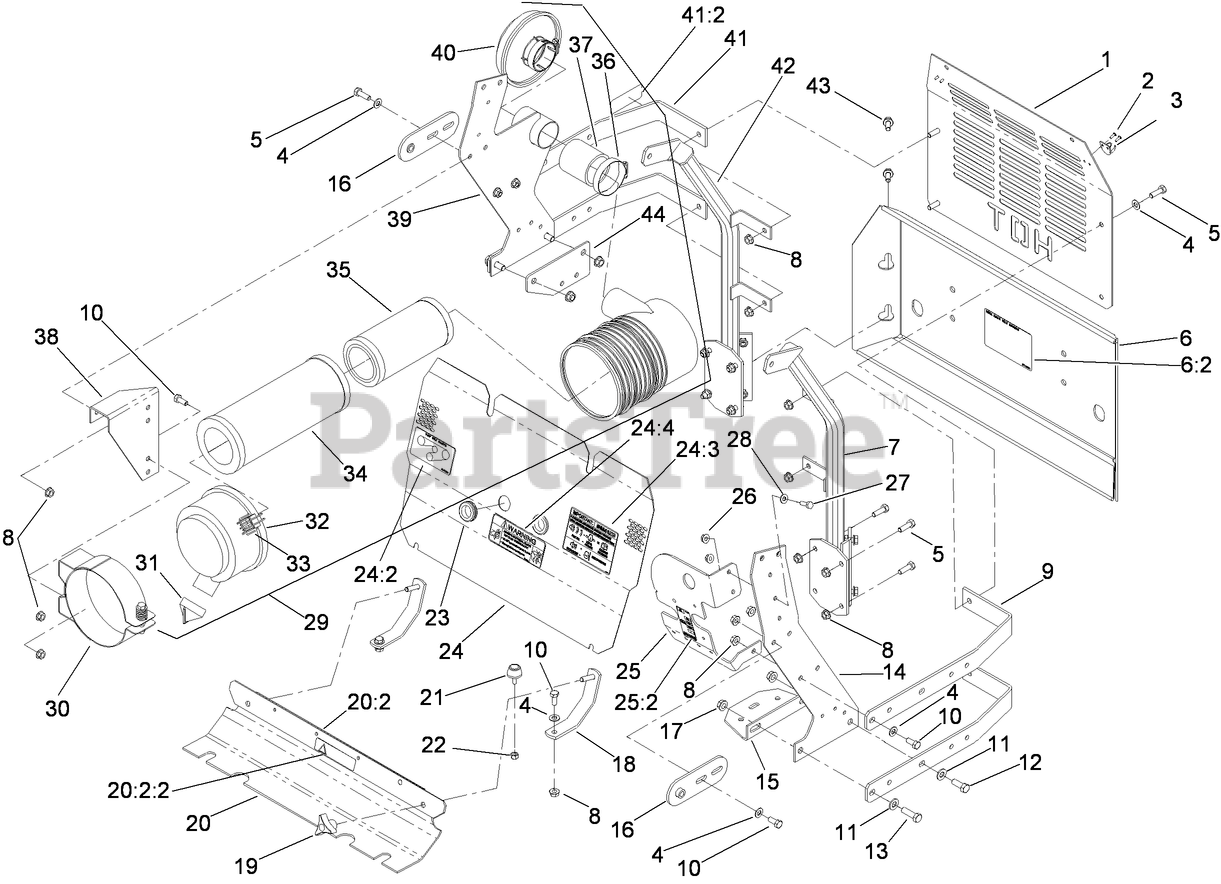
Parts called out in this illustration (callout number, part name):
1	GUARD-MUFFLER
2	RIVET
3	KEEPER-LATCH, RUBBER
4	WASHER-PLAIN
5	SCREW-HH
6	REAR BUMPER ASM
6:2	DECAL-BELT ROUTING, DECK DRIVE
7	FRAME-UPPER, LH REAR
8	NUT-HF
9	BAR-MOUNT FRAME, RADIATOR
10	SCREW-HH
11	WASHER-FLAT
12	SCREW-HH
13	SCREW-HH
14	MOUNT-SIDE, LH
15	BRACKET-BOTTLE
16	SHACKLE-HINGE
17	NUT-HHF, WHIZ
18	MOUNT-BELT SHIELD, ENGINE
19	KNOB-3 PRONG
20	ENGINE BELT SHIELD ASM
20:2	STRIP-SHIELD, BELT
20:2:2	DECAL-COVER, MISSING
21	BUMPER-RUBBER
22	NUT-LOCK, NI
23	GROMMET-RUBBER
24	ENGINE ACCESS PANEL ASM
24:2	DECAL-BELT ROUTING, PUMP
24:3	DECAL-BUZZER, WARNING
24:4	DECAL-DEVICES, ROTATING
25	FUSE/RELAY BRACKET ASM
25:2	DECAL-FUSE
26	NUT-HF
27	SCREW-HH
28	WASHER-FLAT
29	FILTER-AIR
30	BRACKET-FILTER, AIR
31	VALVE-EJECTOR, DUST
32	COVER-FILTER, AIR
33	LATCH-CLEANER, AIR
34	FILTER-AIR
35	FILTER-AIR, SAFETY
36	CLAMP-HOSE
37	HOSE-INTAKE
38	MOUNT-CLEANER, AIR
39	RH RADIATOR AND AC SUPPORT ASM
40	HOOD-CLEANER, 2" AIR INTAKE
41	BAR-RADIATOR
41:2	DECAL-SURFACE, HOT
42	FRAME-UPPER, RH REAR
43	SCREW-HHF
44	PLATE-FUEL FILTER MOUNT
